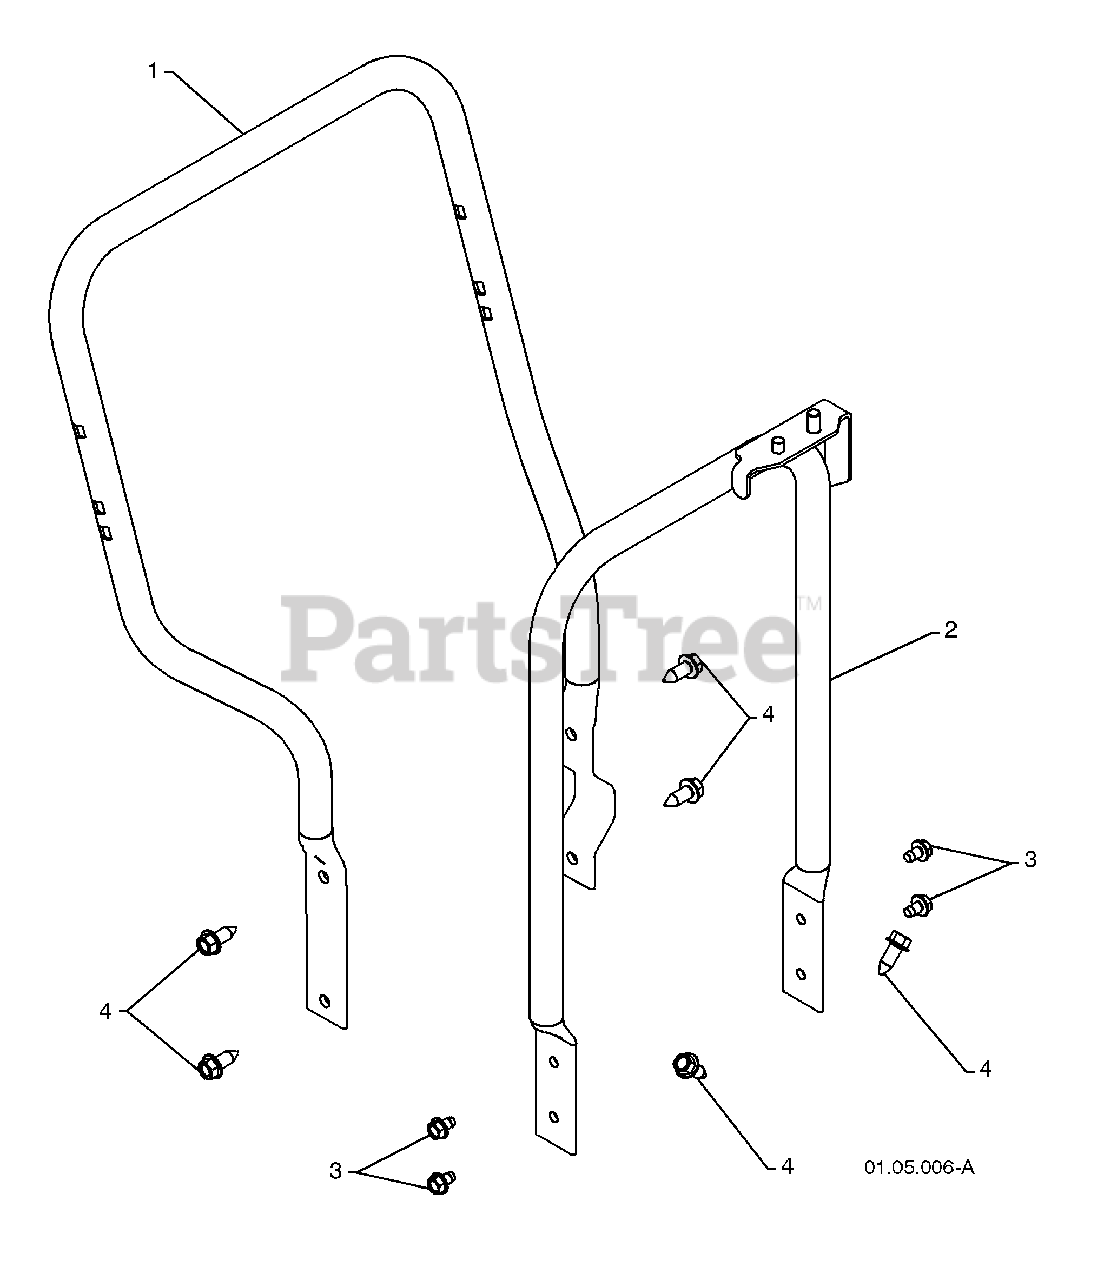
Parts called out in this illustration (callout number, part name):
1	LOWER TUBE GRAY
2	PIVOT SUPPORT
3	BOLT 5/16-18 X .500
4	SCREW 3/8-16 X 1.00
